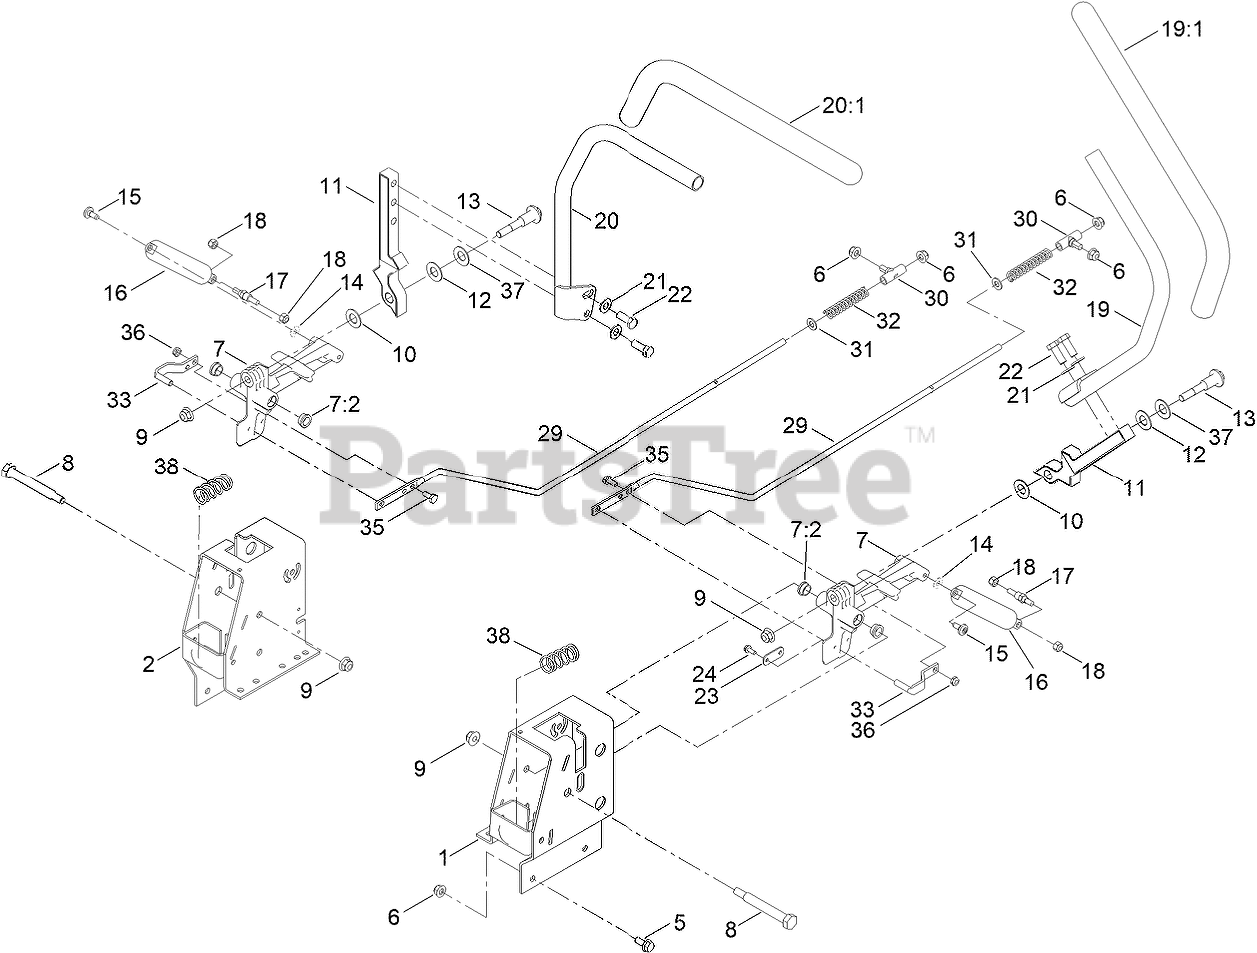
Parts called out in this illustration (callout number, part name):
1	BOX-CONTROL, LH
2	BOX-CONTROL, RH
5	SCREW-HHF
6	NUT-HF, NI
7	ACTUATOR ARM ASM
7:2	BUSHING-FLANGE
8	BOLT-PIVOT
9	NUT-HF, NI
10	WASHER-NYLON
11	ARM-CONTROL
12	WASHER
13	BOLT-PIVOT
14	WASHER
15	SCREW-SHOULDER
16	DAMPER-NON CAVITATING
17	STUD-DAMPER
18	NUT-LOCK, NI
19	HANDLE-CONTROL, LH
20	HANDLE-CONTROL, RH
21	WASHER-FLAT
22	SCREW-HH
23	PLATE-STOP, HYDRO
24	SCREW-TAPTITE
29	ROD-HYDRO
30	MOUNT-ROD, HYDRO
31	WASHER-PLAIN
32	SPRING-COMPRESSION
33	PIN-ROD, HYDRO
35	SCREW-HH
36	NUT-LOCK, NI
37	WASHER-BELLEVILLE
38	SPRING-RETURN
